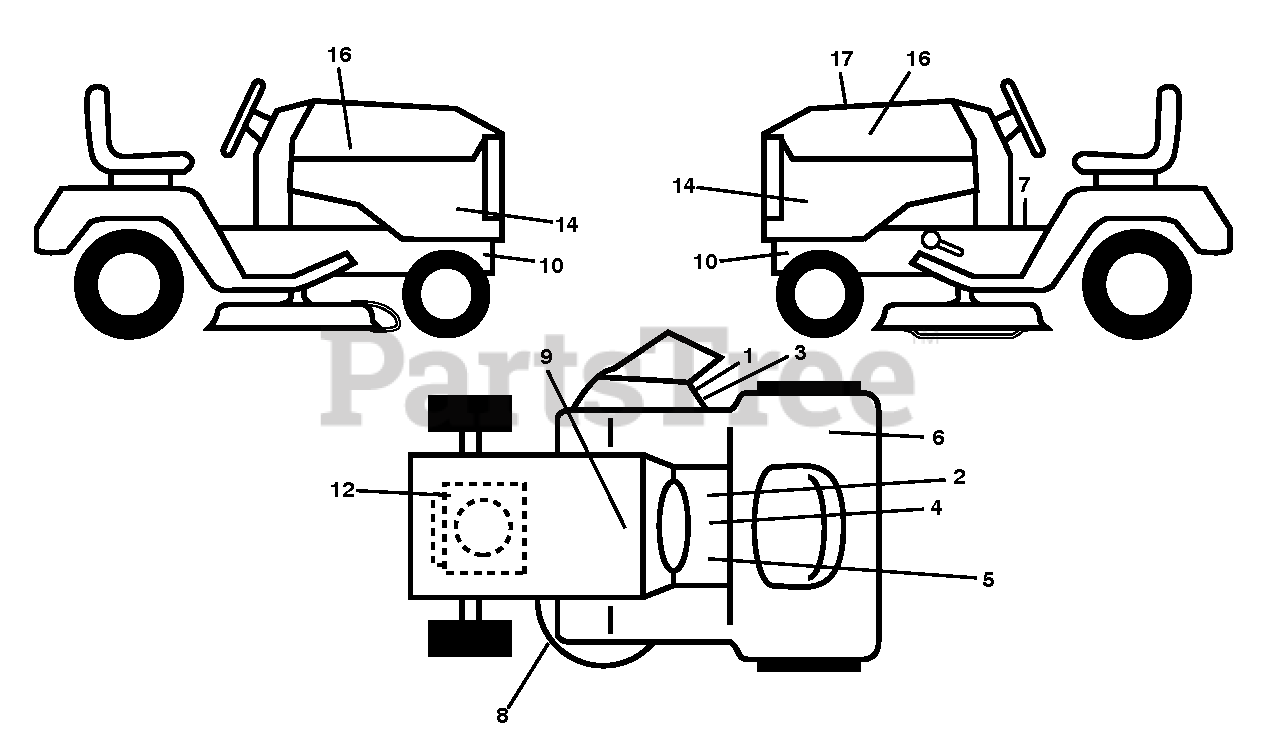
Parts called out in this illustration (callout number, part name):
1	DECAL.INTERNATIONL.CUTFINGER
2	DECAL
3	DECAL, DEFLECT WARNING
4	DECAL PARK BRAKE
5	LABEL
6	Decal, Fender 100 DB/CE
7	DECAL
8	DECAL V BELT SCHEMATIC
9	DECAL BTRY SYMBOLS
12	DECAL
16	RP.DECAL.BADGE.170MM.TEXTLOGO
